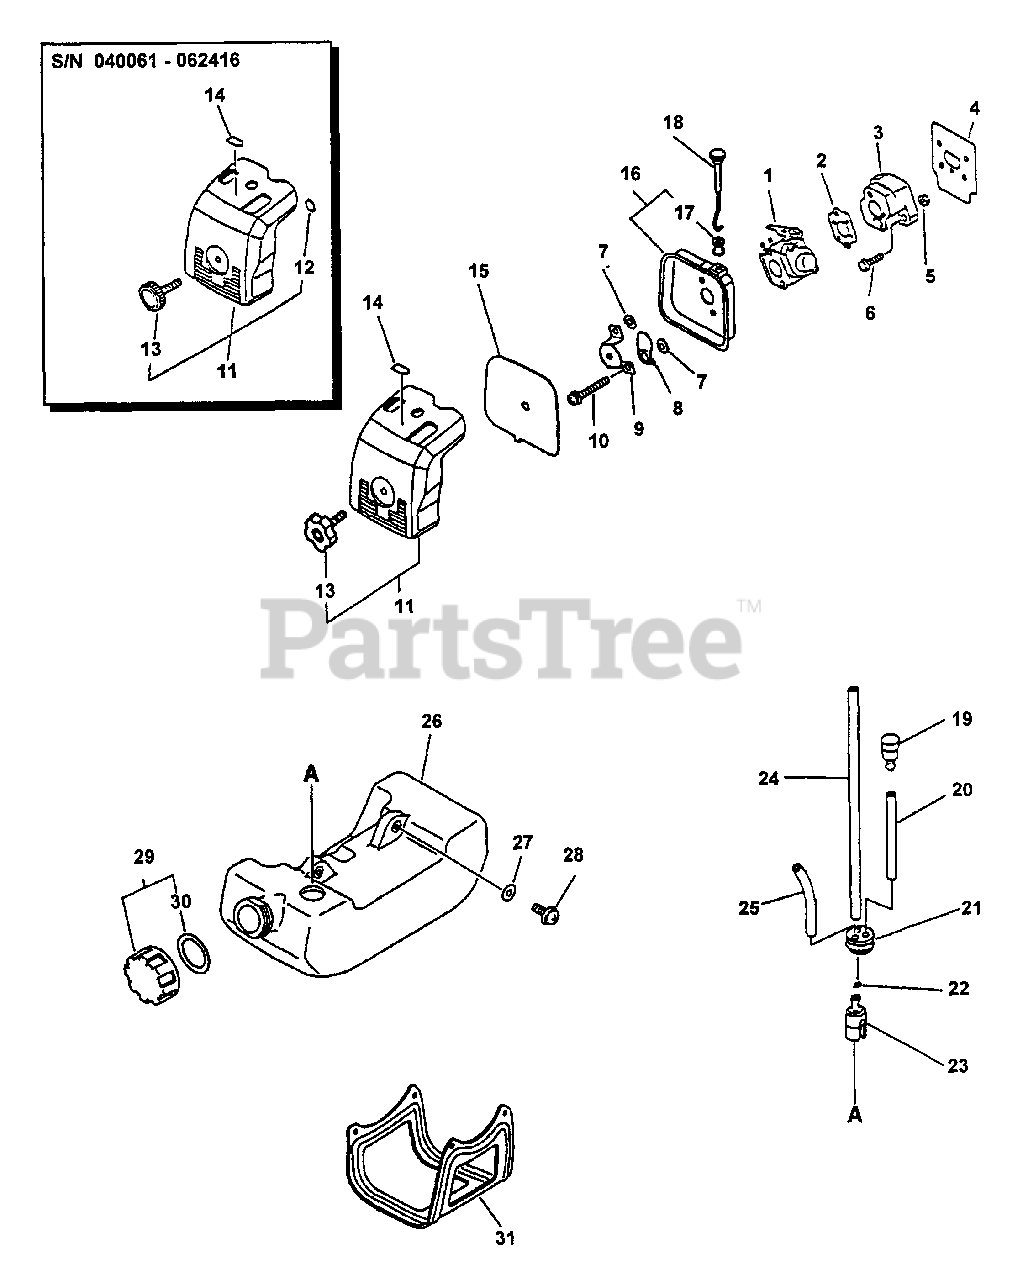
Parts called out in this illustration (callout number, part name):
1	CARBURETOR - C1U-K23A
1	CARBURETOR - WT-424A
2	GASKET, INTAKE
2	GASKET, CARBURETOR
3	INSULATOR, INTAKE
4	HEAT SHIELD, INTAKE
5	NUT M5
6	SCREW 5×20
7	WASHER 5.2×8×0.8T
8	SHUTTER, CHOKE
9	PLATE, PREVENT
10	SCREW 5×57
11	AIR FILTER COVER ASSY
12	O-RING 3
13	THUMBSCREW
14	LABEL - CHOKE
15	FILTER, HEAVY-DUTY AIR
16	CASE, AIR FILTER
17	GROMMET, CHOKE
18	ROD, CHOKE
19	VENT ASSY
20	PIPE, FUEL 3x-5x-70 BLACK
21	GROMMET, FUEL
22	CLIP 6 MM
23	FILTER, FUEL
24	PIPE, FUEL 3x-5x-180
25	PIPE, FUEL RETURN 3×6×90 MM CLEAR
26	TANK, FUEL
27	WASHER 5.5×12×0.8
28	SCREW 5×16
29	CAP ASSY
30	GASKET, FUEL CAP
31	GUARD, FUEL TANK
